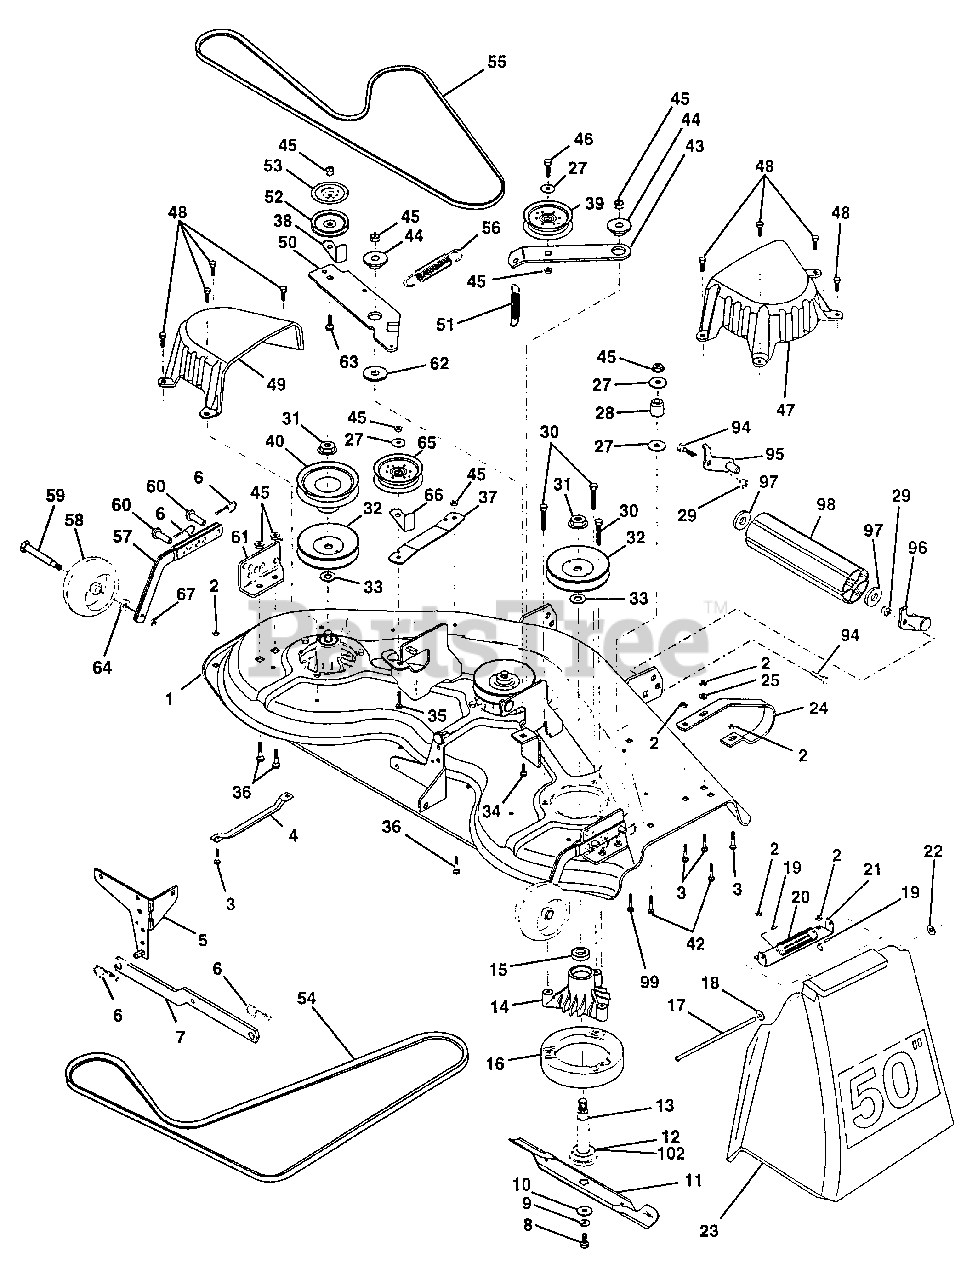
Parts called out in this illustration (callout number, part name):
1	Deck Asm., Mower 50" Vented (AYP part number)
2	Nut, Crownlock 5/16-18
3	Bolt, Carriage 5/16-18 x 3/4
4	Runner, Mower LH
5	Bracket Asm., Sway Bar
6	Retainer, Spring (AYP part number)
7	Arm Suspension, Rear (AYP part number)
8	Bolt 3/8-24 x 1.25 Gr. 8 Patched
9	Washer, Lock Hvy 3/8 Unplated (AYP part number)
10	Washer, Hard Blade Mower Vented
11	Blade
12	Bearing, Ball #6204 (Mandrel)
13	Shaft Asm., W/Lower Brg
14	Housing, Mandrel 50" Vent
15	Bearing, Ball Mandrel
16	Stripper, Mower Vented (AYP part number)
17	Rod, Hinge
18	Washer 11/32 x 5/8 x 16 Ga.
19	Spring, Torsion Deflector
20	Spring, Torsion Deflector
21	Bracket, Deflector
22	Nut, Push
23	Shield, Deflector Mower
24	Runner, RH
25	Washer 11/32 x 3/4 x 16 Ga.
27	Washer 13/32 x 13/16 x 16 Ga.
28	Spacer, Spring Stop Idler (AYP part number)
29	Nut, Lock Hex W/Wsh 3/8-16 Unc
30	Screw Thd Rolling Washer Head (AYP part number)
31	Nut, Flg Top Lock Cntr 9/16
32	Pulley, Mandrel (AYP part number)
33	Washer, Spacer Mower Vented (AYP part number)
34	Bolt, Carriage 3/8-16 x 1-1/4
35	Bolt, Carriage 3/8-16 x 2
36	Bolt, Carriage 3/8-16 x 1 Gr. 5
37	Stiffener, Arm Idler
38	Keeper, Belt Idler (AYP part number)
39	Pulley, Idler Flat (AYP part number)
40	Pulley, Driven
42	Bolt, Carriage 5/16-18 Unc x 3/4
43	Arm, Idler Secondary
44	Spacer, Retainer
45	Nut, Crownlock 3/8-16 Unc
46	Bolt, Fin Hex 3/8-16 Unc x 1-3/4
47	Cover, Mandrel RH
48	Screw, Thd Roll 1/4-20 x 5/8
49	Cover, Mandrel LH
50	Arm, Idler Primary
51	Spring, Secondary
52	Pulley, Idler V Groove
53	Shield, Idler
54	V-Belt, Mower Primary
55	V-Belt, Mower Secondary
56	Spring, Primary
57	Bar Asm., Wheel Gauge
58	Wheel, Gauge
59	Bolt, Shoulder (AYP part number)
60	Pin, Clevis
61	Bracket, Wheel Gauge
62	Washer Hardened (AYP part number)
63	Bolt Carriage 3/8-16 x 1-1/2
64	Washer 3/8 x 7/8 x 14 Ga.
65	Pulley Idler Flat Mower (AYP part number)
66	Keeper, Belt Idler 50" Vent
67	Nut, Center Lock 3/8-16
94	Bolt H 3/8-16 x 1
95	Bracket, Asm. Noseroller LH (AYP part number)
96	Bracket, Asm. Noseroller RH (AYP part number)
97	Washer 17/32 x 7/8 x 16 Ga.
98	Roller, Nose (AYP part number)
99	Bolt, Carriage 3/8-16 x 1-3/4 Gr. 5
102	Washer Felt
